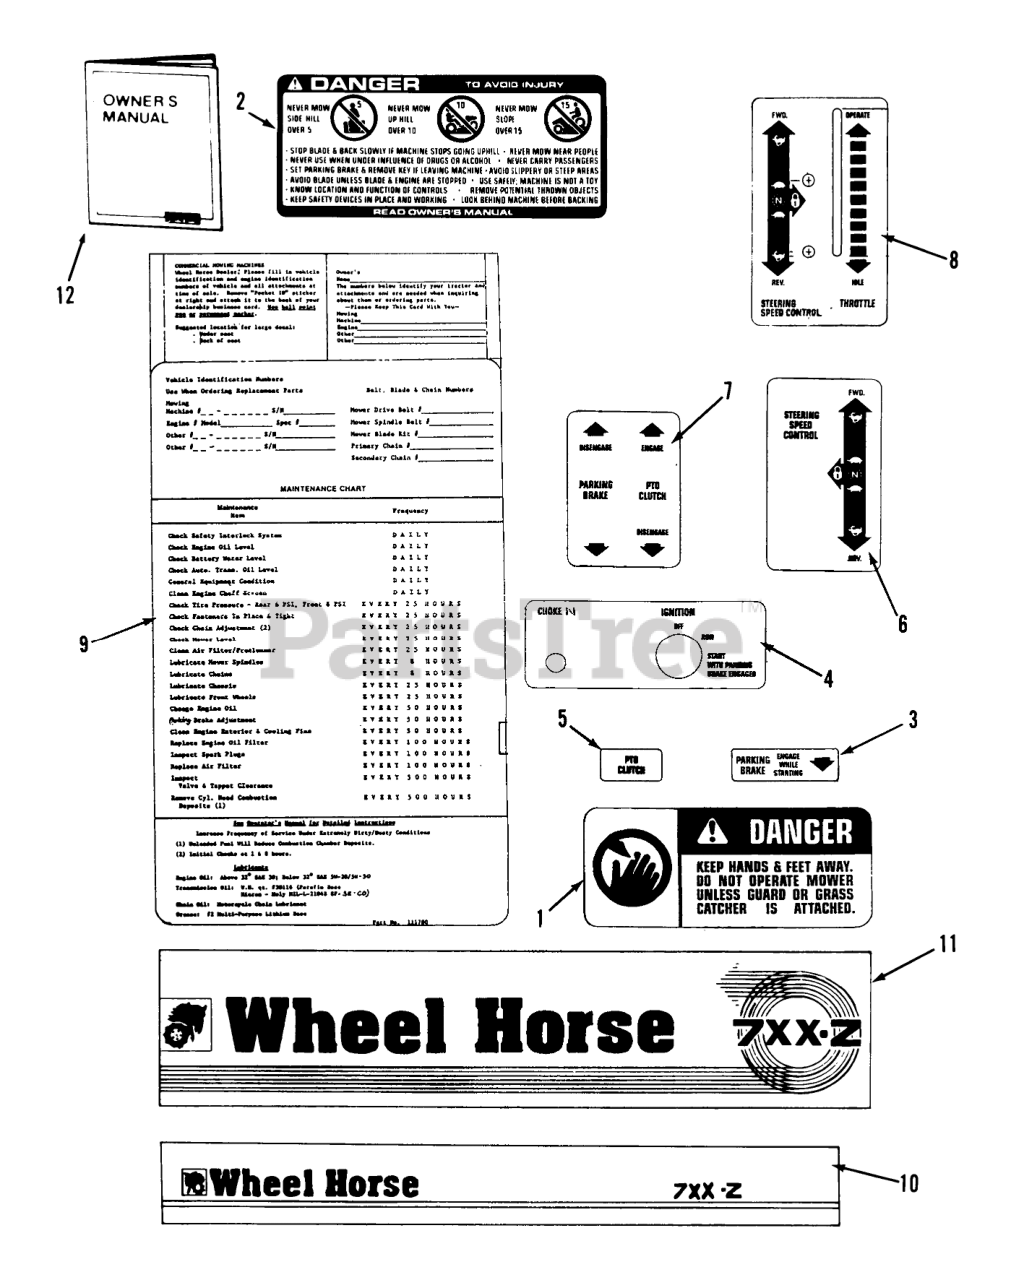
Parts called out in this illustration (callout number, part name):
1	Danger Decal
2	DECAL-DANGER
3	DECAL-PARKING BRAKE
4	DECAL-CHOKE/IGNITION
5	Decal-PTO Clutch
6	Decal-SpeedControl
7	DECAL-PARKING BRAKE
8	Decal-Steering/Throttle
9	Decal-Maintenance
10	DECAL-FRONT
10	DECAL FRONT
11	DECAL-FENDER RH
11	Decal-Rear Fender RH 720-Z
11	DECAL-FENDER LH
11	Decal-Rear Fender LH 720-Z
12	700-Series Owner-s Manual
